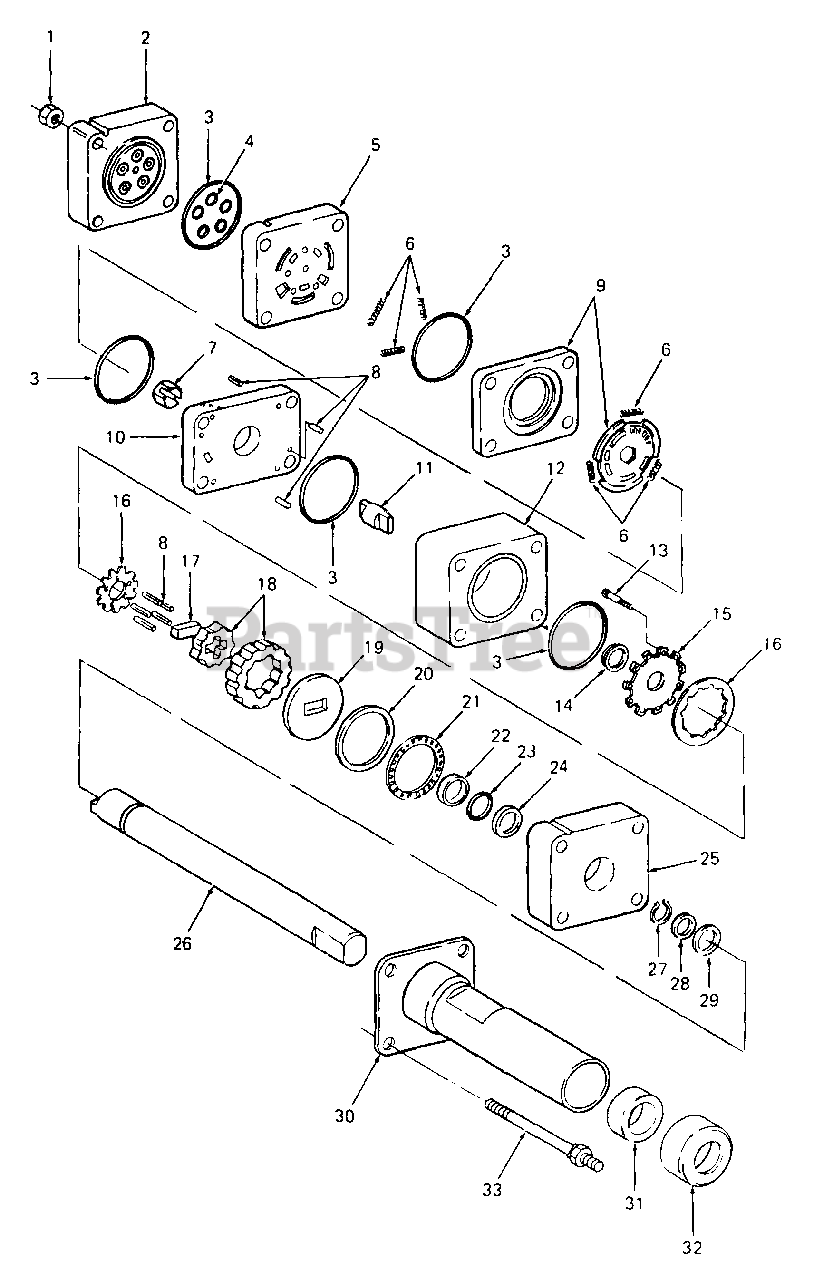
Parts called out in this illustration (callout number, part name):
1	Nut, Hex, 5/16-24
2	Power Cover & Check Valve Assy
3	Ring, Seal
5	Manifold, Port
7	Drive Assy, Hex
8	Roller Kit, Needle
9	Valve & Ring Assy
10	Manifold, Isolation
12	Ring, Metering
15	Cover, Commutator
16	Commutator & Ring Assy
17	Spacer, Drive Link
21	Bearing, Thrust
22	Seal, Face
23	Ring, Back-up
24	Seal, Spacer
25	Plate, Upper Cover
26	Input Shaft Assy
27	Ring, Retaining
29	Plate, Retaining
30	Upper Cover & Tube Assy w/Flat
31	Bearing, Column
32	Dust Seal, Column
33	Bolt, Special
